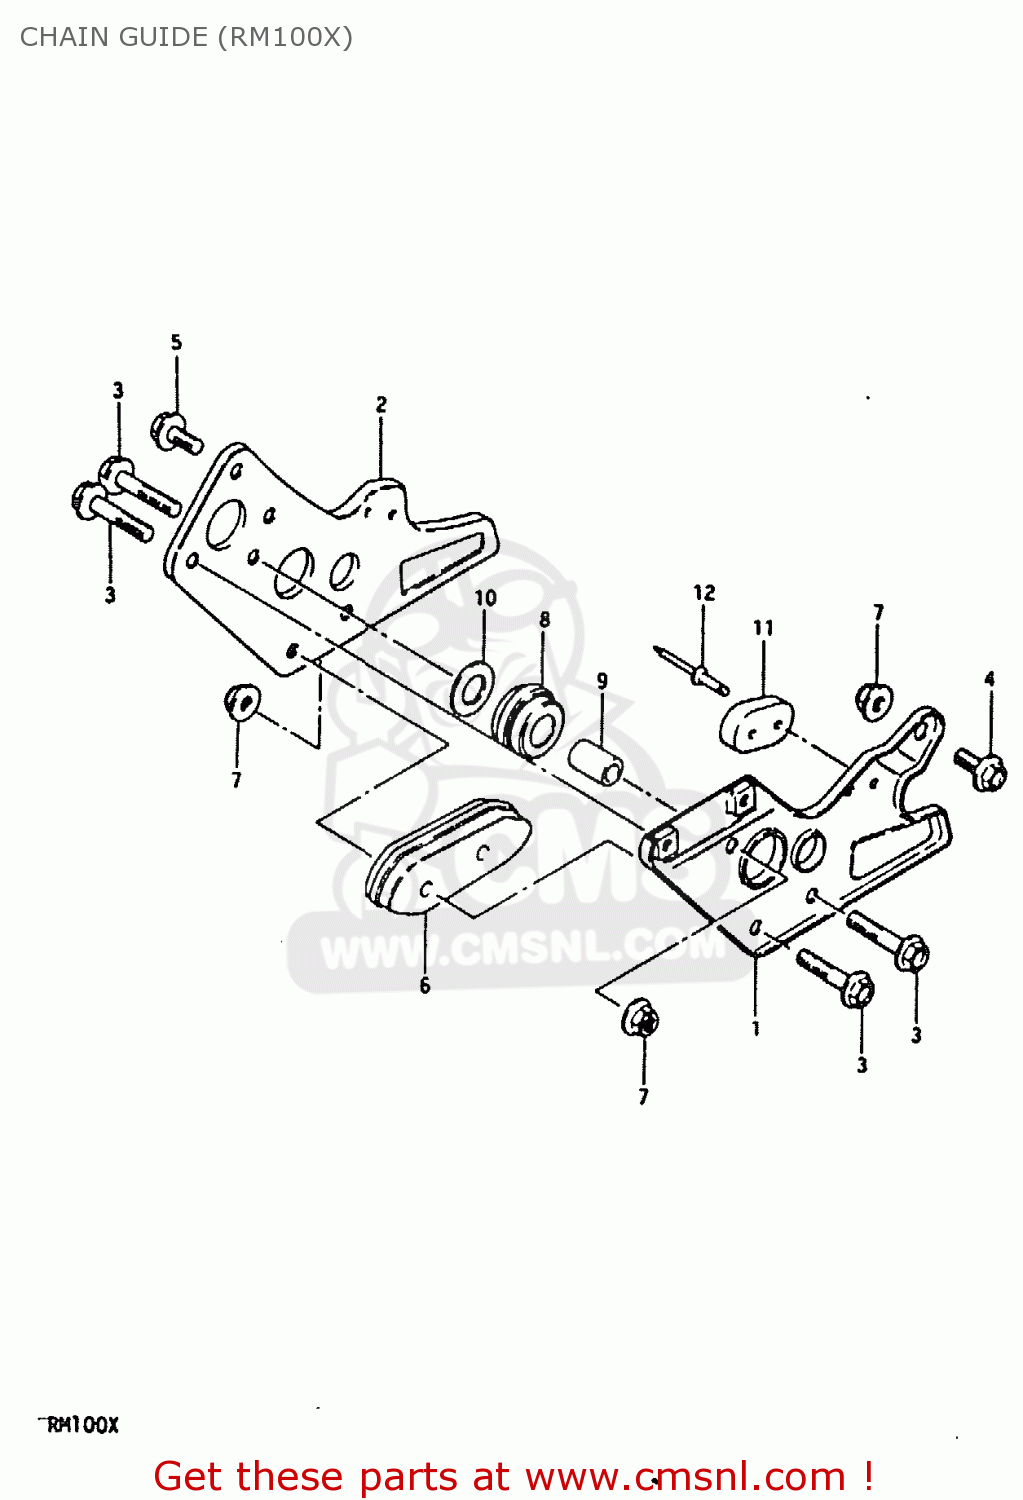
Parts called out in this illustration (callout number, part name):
1	PLATE,CHAIN GUIDE,OUTER
2	PLATE,GUIDE CHAIN
3	BOLT 6X35
4	BOLT
5	BOLT
6	DEFENSE,CHAIN GUIDE
7	NUT
8	ROLLER,CHAIN GUIDE
9	SPACER,CHAIN GUIDE ROLLER
10	WASHER
11	PAD,DRIVE CHAIN GUIDE
12	RIVET
